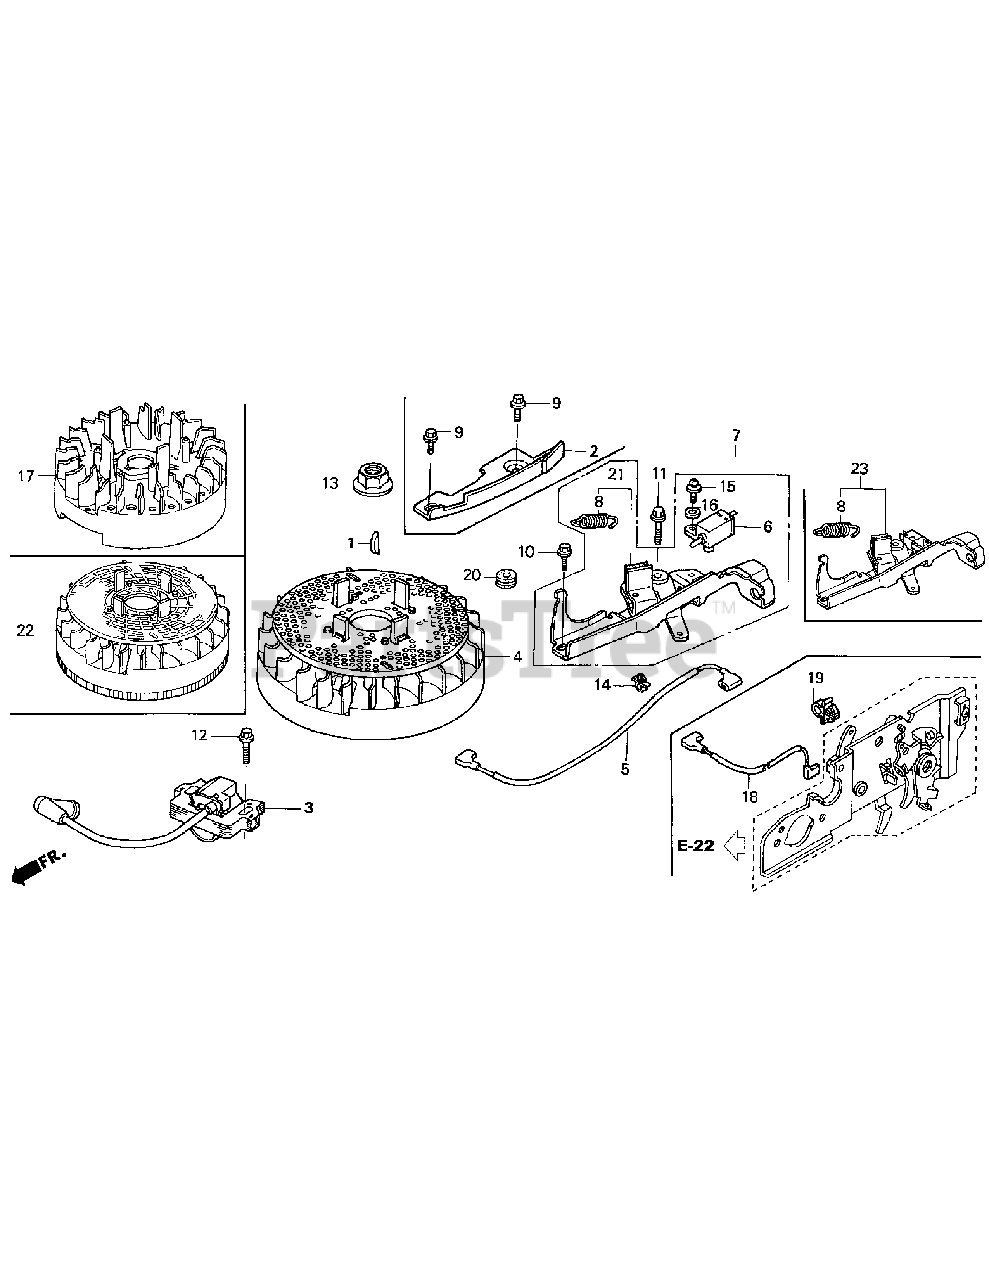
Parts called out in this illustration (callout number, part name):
1	KEY, SPECIAL WOODRUFF (25X18)
2	PLATE, SIDE
3	COIL ASSY., IGNITION
9	BOLT, FLANGE (6X12) (CT200)
12	BOLT, FLANGE (6X20) (CT200)
13	NUT, SPECIAL (14MM)
